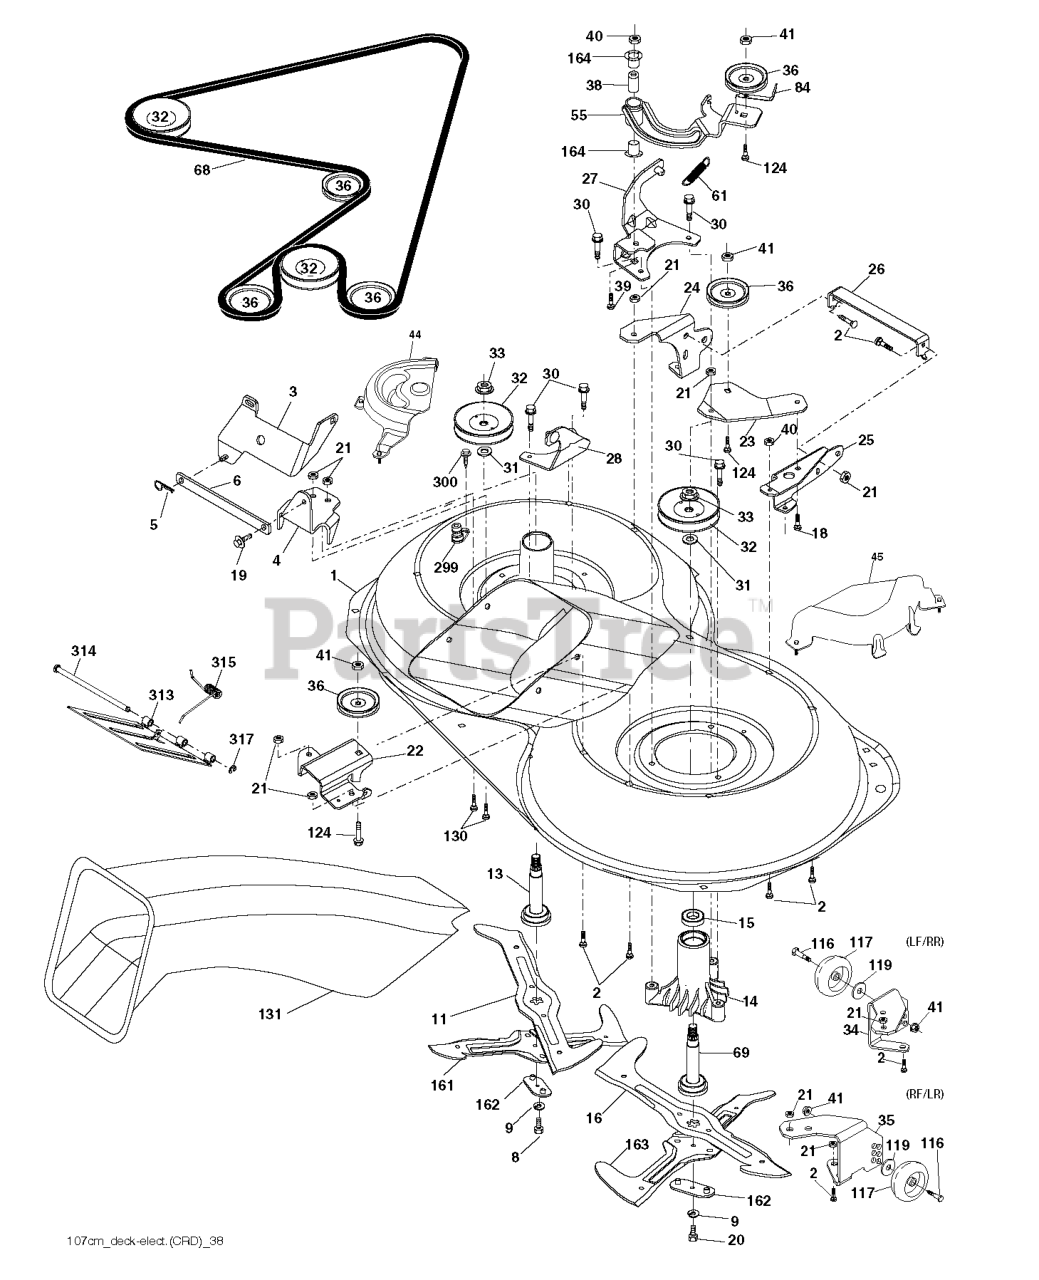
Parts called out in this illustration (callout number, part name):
2	RP BOLT 5/16-18 X3/4 ZN/YEL GR
3	BRACKET.ASM.BAR.SWAY.CHASS
5	RETAINER-SPRNG RB
6	BAR.SWAY.92.CRD
8	BOLT.3/8-24X1.25 GR8
9	LOCKWASHER
11	BLADE.3N1.LH.CRD
13	SHAFT ASM VENT
14	HOUSING.MANDREL.VENTED (MACHD)
16	BLADE.3N1.RH.CRD
19	BOLT SHD 5/16-18
20	BOLT.3/8-24X1.25GR8. LHTHRD
21	LOCKNUT
22	BRACKET.IDLER.RR.107.CRD
24	BRACKET
25	BRACKET RF
26	SUPPORT
28	BRACKET
30	SCREW, WASHER HEAD
31	WASHER.SPACER.MANDREL
32	PULLEY.MANDREL.4.80 PD.2006
33	NUT.FLANGE.LOCK.TOP
34	BRACKET
35	BRACKET
36	PULLEY.IDLER.4.25
41	NUT LOCK FLG 3/8-16 UNC
55	ARM.IDLER.107.CRD
61	SPRING
68	HEX-BELT 107 MOWER
69	SHAFT.ASM.W/LWR.BRG.RH.THREAD
84	KEEPER, BELT IDLER
116	BOLT.SHOULDER.3/8-16X3-5/8.
117	RP WHEEL. GUAGE RALLY
119	WASHER
124	BOLT.3/8-16X1.50
130	BOLT.CARR.SQNK.5/16-18UNC.X3/4
163	BLADE.CROSS.RH.CRD.107
164	BRNG T
299	PORT.WASHOUT
300	SCREW.TT.#10-32X.5.3/8.FLANGE
313	COVER DOOR.107 CM CRD EZ MULCH
314	PIN PIN.HINGE
317	E-RING.5/16"
